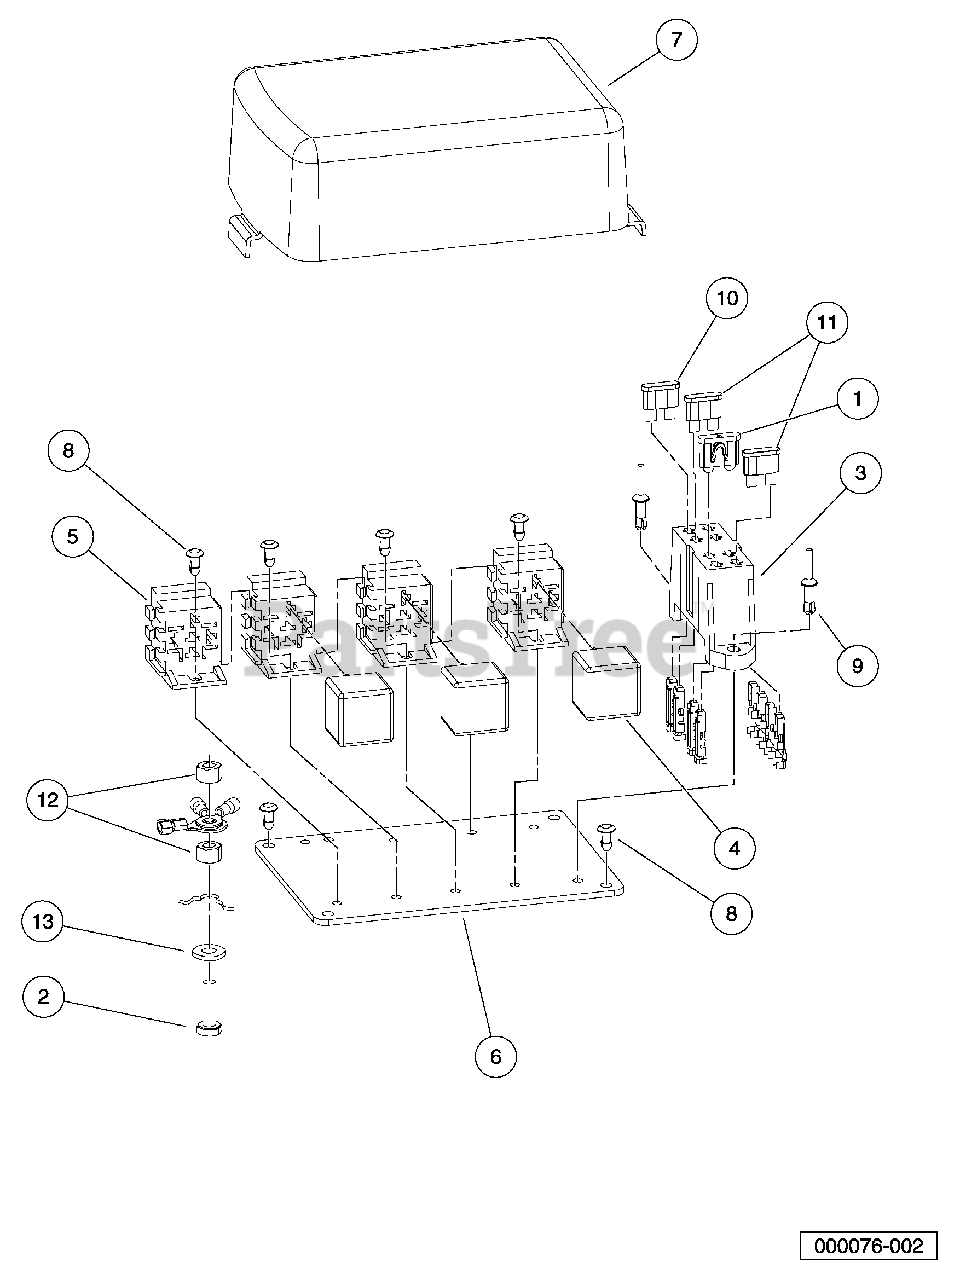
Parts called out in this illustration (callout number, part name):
1	Fuse, 10-Amp.
2	Screw, 1/4-20 X .88 Hex Hd Cap
3	Fuse Block
4	Relay, Mini ISO, SPDT
5	Connector, Relay
6	Plate, Electrical.
7	Cover, Electrical
8	Fastener, Push-in
9	Rivet, Drive
10	Fuse, 25-Amp.
11	Fuse, 30-Amp.
12	Locknut, 1/4-20 Dimpled
13	Washer, 1/4 Type A Narrow Flat
